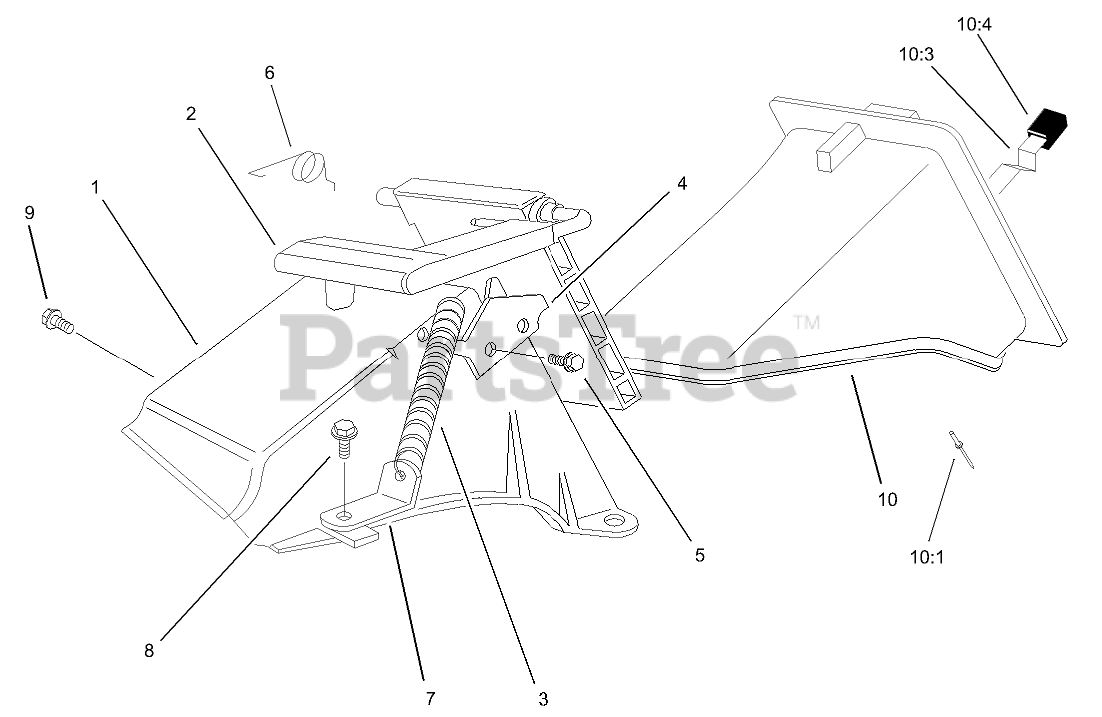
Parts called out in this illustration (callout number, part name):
1	TUNNEL-DISCHARGE
2	DISCHARGE DOOR ASM
3	SPRING-DOOR
4	LATCH-PLATE
5	SCREW-PLASTITE
6	RETAINER-DOOR
7	BRACKET-SPRING
8	SCREW-HWH
9	SCREW AND WASHER ASM
10	DISCHARGE PLUG ASM
10:1	RIVET-HEAD, FLAT
10:3	LATCH-PLUG, DISCHARGE
10:4	GRIP-LATCH
